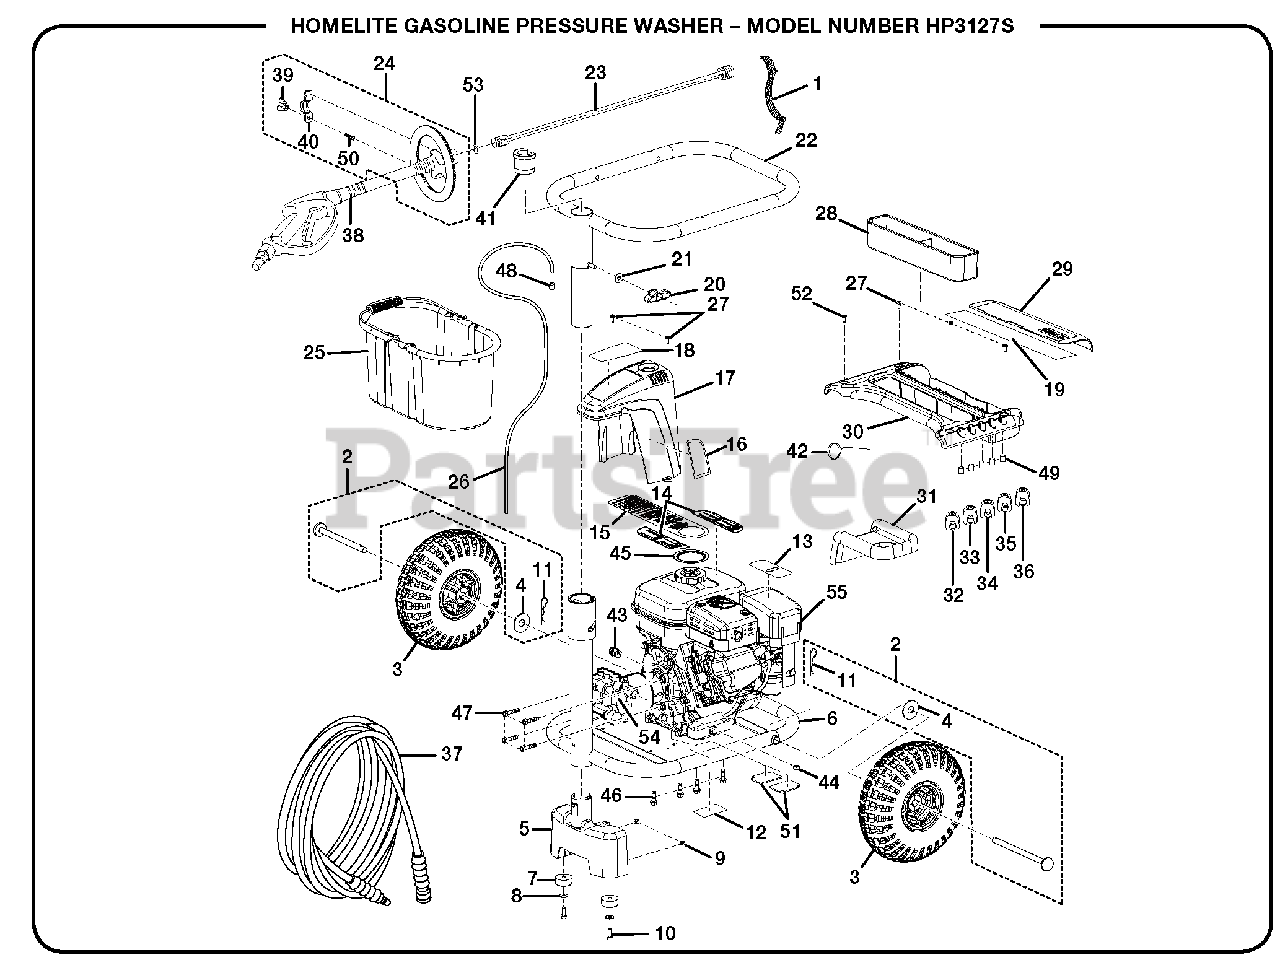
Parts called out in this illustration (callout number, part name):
1	HOOK AND LOOP STRAP
2	BAGGED AXLE ASSEMBLY (INC. KEY NOS. 4 AND 11)
3	WHEEL ASSEMBLY
6	LOWER TUBE BODY
9	NYLON LOCK NUT (1/4-20)
10	SCREW (1/4-20 X 3/4 in. HEX HD.)
11	HITCH PIN
12	DATA LABEL.
13	LABEL, HOT SURFACE WARNING
14	LABEL, WARNING
15	LABEL, CAUTION
16	LABEL, PUMP DESIGNATOR
17	PUMP COVER
18	LABEL, QUICK START GUIDE
19	QUICK START GUIDE
20	KNOB (5/16 in.)
21	WASHER (5/16 in.)
22	UPPER TUBE BODY
23	SPRAY WAND EXTENSION
24	HANDLE ASSEMBLY (INCLUDES KEY NOS. 39, 40 AND 50)
25	DETERGENT BUCKET
26	INJECTION HOSE
27	SCREW (12-14 TYPE B THREAD)
28	TRAY INSERT
31	GAS SPILL COVER
32	NOZZLE 0deg
33	NOZZLE 15deg
34	NOZZLE 25deg
35	NOZZLE 40deg
36	NOZZLE, SOAP
37	HIGH PRESSURE HOSE
38	SPRAY WAND
40	CLAMP
41	WAND SLEEVE
42	NOZZLE CLEANING TOOL
43	QUICK DISCONNECT, BRASS
44	HEX NUT (M8)
45	FUEL TANK LOCK RING
46	BOLT (M8 X 40 mm HEX HD.)
47	BOLT (5/16 in.)
48	INJECTION HOSE FILTER
49	GROMMET, NOZZLE STORAGE
50	BOLT (1/4-20 X .609 in. SQ. HD).
51	RUBBER VIBRATION PAD
52	SCREW (12-14 X 15 mm)
54	PUMP
